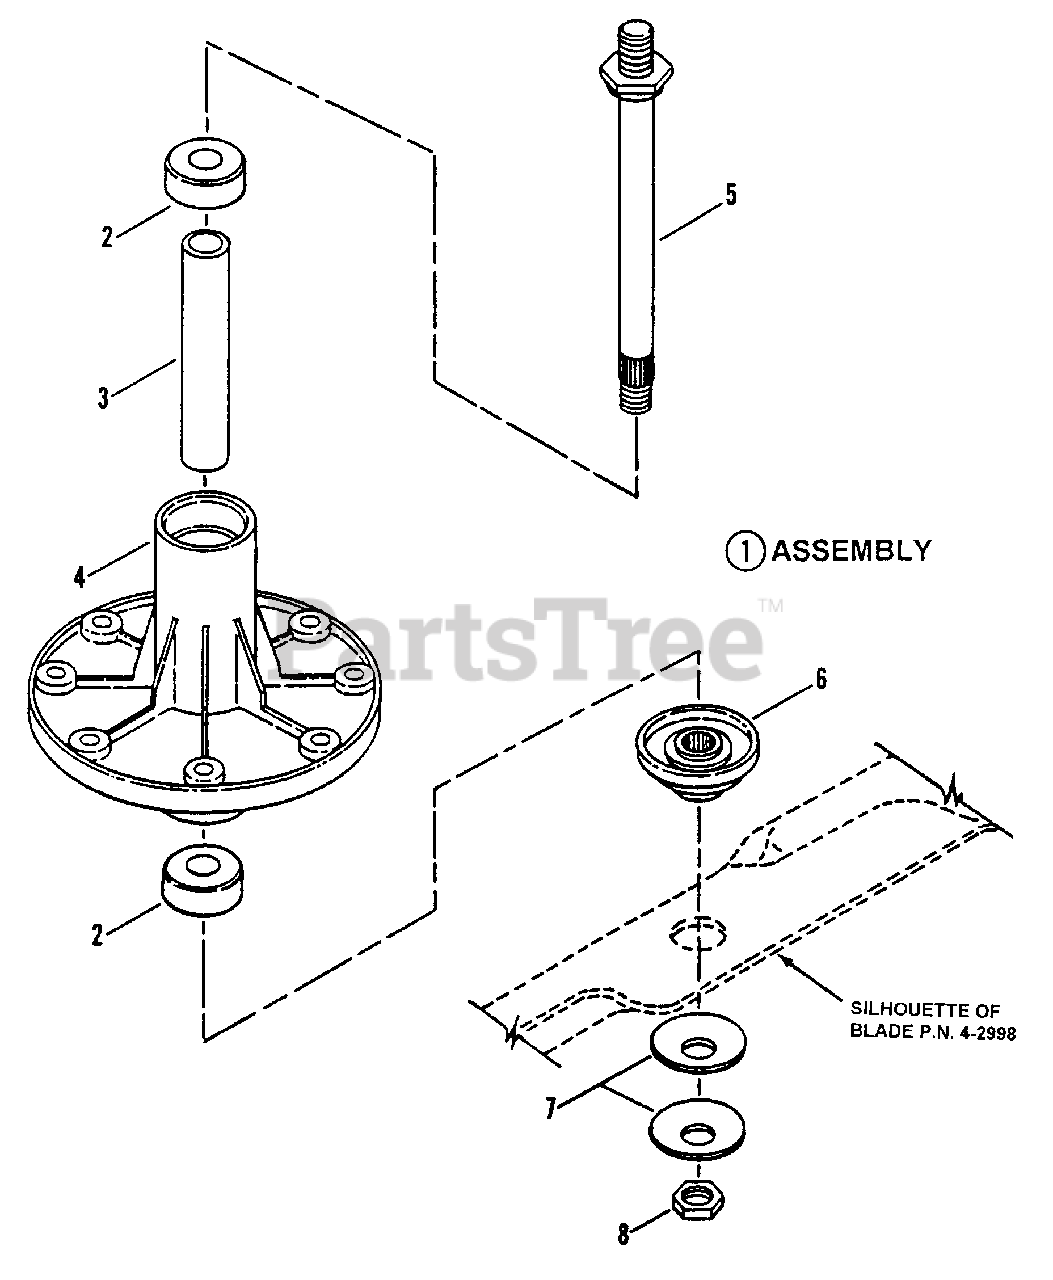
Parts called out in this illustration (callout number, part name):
1	ASSEMBLY, Spindle Housing, 38" Cutting Deck
2	BEARING, Spindle
3	SPACER, Spindle Housing
4	HOUSING, Spindle
5	SPINDLE, 7.019" Long
6	SPACER, Blade
7	WASHER, Belleville, 19/32" I.D. x 1-3/4" O.D.
8	NUT, 9/16-18 Hex Jam
